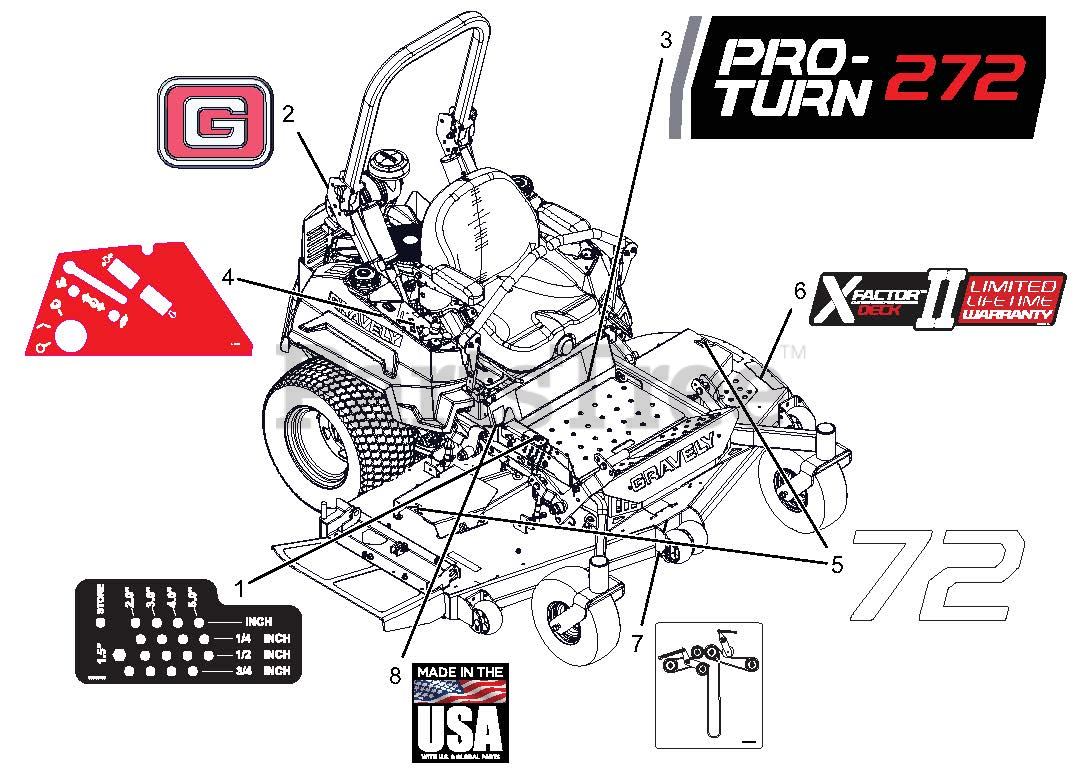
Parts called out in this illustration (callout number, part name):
1	DECAL, HEIGHT OF CUT
2	DECAL, GRAVELY BRAND
3	DECAL, PRO-TURN 272
4	DECAL, EFI CONTROL PANEL
5	DECAL, 72"
6	DECAL, X-FACTOR DECK
7	DCL,BELT ROUTE-RH BK-SIDE IDLR
8	DECAL, MADE IN USA
